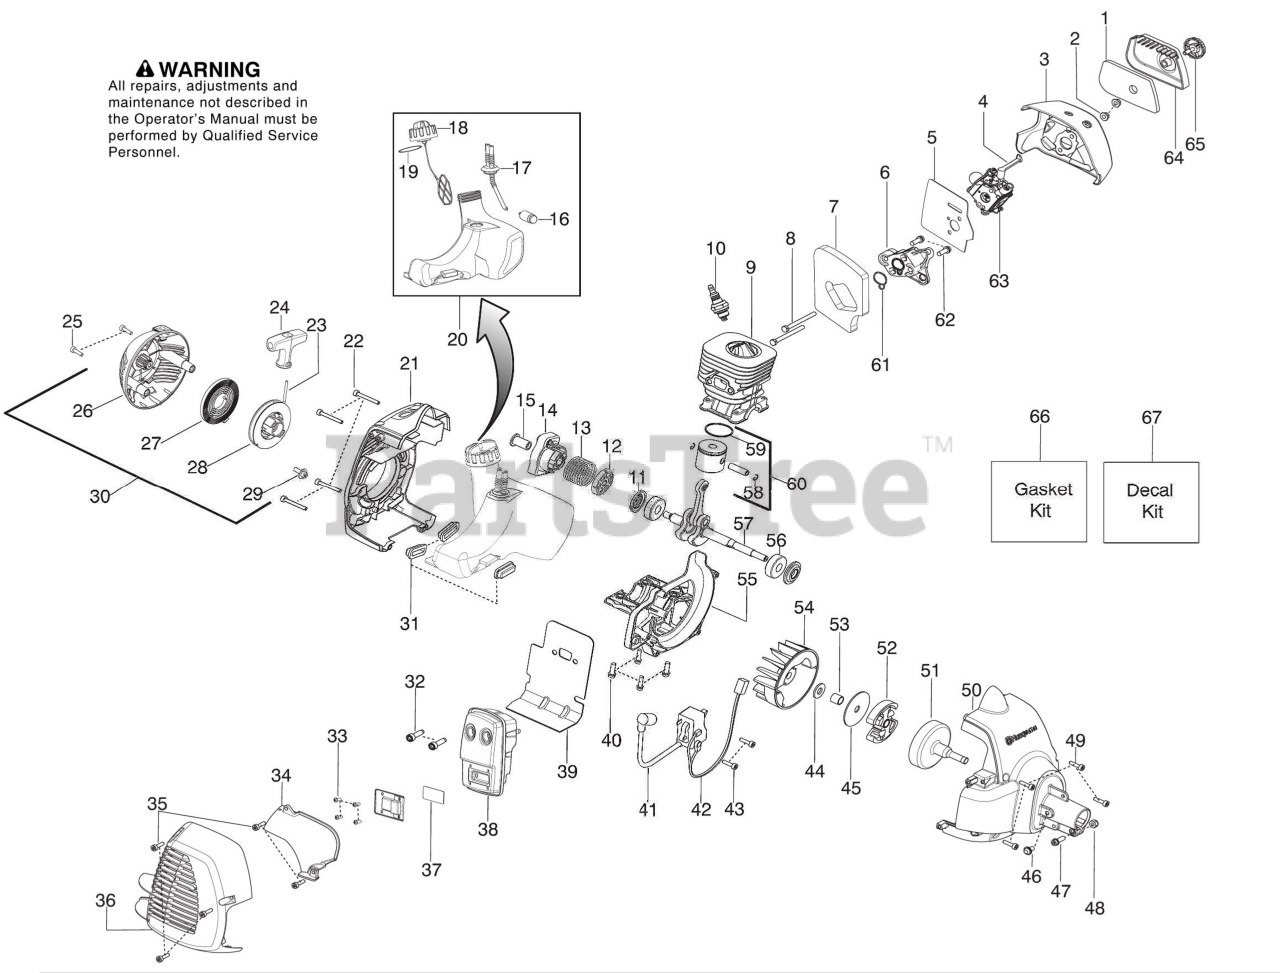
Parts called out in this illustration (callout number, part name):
2	Nut - Carb. Screw
3	Air Box
4	Lever - Choke
5	Kit-Carb. Gasket
6	Adaptor - Carb.
7	Kit - Gasket
9	Cylinder
10	Plug - Spark (RCJ-8Y)
11	Kit - Crankshaft seal
12	Washer - Starter
13	Spring - Starter Cup
14	Assy - Starter Cup
15	Coupling - Starter
16	Assy - Fuel Filter
17	Kit - Fuel Line
18	Assy - Cap w/ret.
19	Kit Gasket O-ring - Fuel Cap
20	Assy - Fuel Tank
21	Shroud - Rear
23	Kit - Rope
24	Handle - Starter
26	Starter Hsg. w/eyelet
27	Kit - Starter Spring
28	Kit - Starter Pulley
30	Assy - Starter Hsg
31	Isolator - Tank
32	Bolt - Muffler
33	Screw
34	Shield - Heat
36	Guard - Muffler
37	Kit - Spark Arrestor
38	Assy - Muffler
39	Kit - Gasket-paper met
41	Module - Ignition
42	Assy - Leadwire
45	Washer - Clutch
50	Assy - Fan Housing
51	Assy - Clutch Drum
52	Kit - Clutch Assy.
57	Kit - Crankshaft
58	Retainer - Piston Pin
59	Ring - Piston
60	Kit - Piston
61	Kit - Gasket
63	Kit - Carb.
64	Cover - Air Box
65	Assy - Knob
66	Kit - Gasket
67	Kit - Decal
